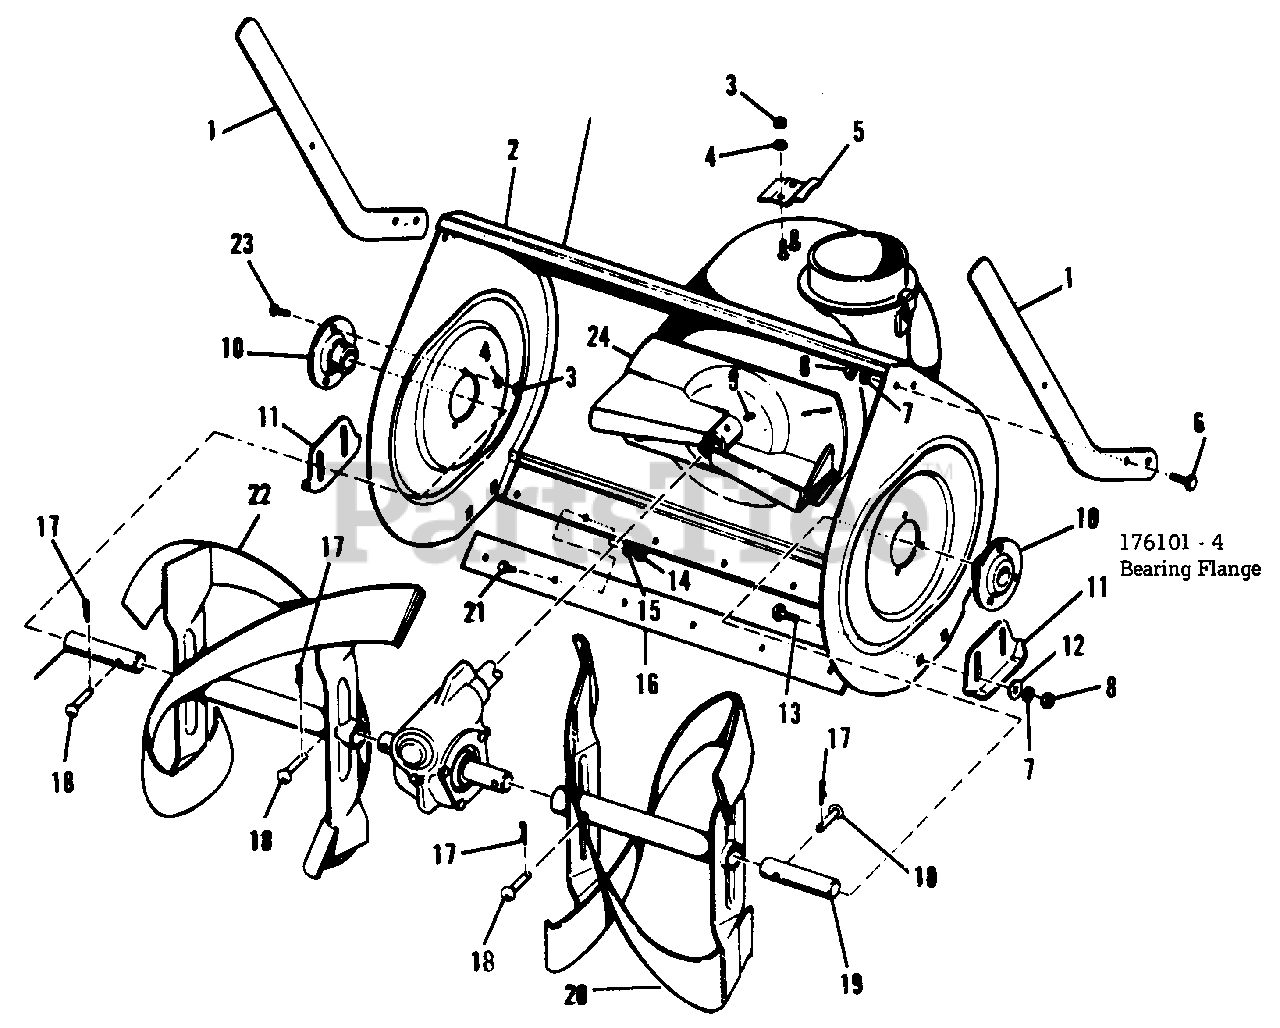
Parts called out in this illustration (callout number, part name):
1	CUTTER-drift, 3/16 x 1-1/2 x 18 3/8
2	BODY ASSEMBLY
3	NUT-hex, 5/16-18
4	WASHER-lock, 5/16
5	CLIP-hold down
6	SCREW-hex cap, 3/8-16 x 3/4
7	WASHER-lock, 3/8
8	NUT-full hex, 3/8-16
9	SCREW-set, 5/16-18 x 3/8
10	BEARING ASSEMBLY
12	WASHER-flat, 3/8
13	BOLT-carriage, 3/8-16 x 3/4
14	NUT-full hex, 1/4-20
15	WASHER-lock, 1/4
16	BLADE-scraper
17	PIN-cotter, 1/8 x 1
18	PIN
19	AUGER-shaft
20	AUGER ASSEMBLY- L.H.
21	SCREW-hex cap, 1/4-20 x 5/8
22	AUGER ASSEMBLY-R.H.
23	SCREW-hex cap, 5/16-18 x 3/4
24	IMPELLER ASSEMBLY
